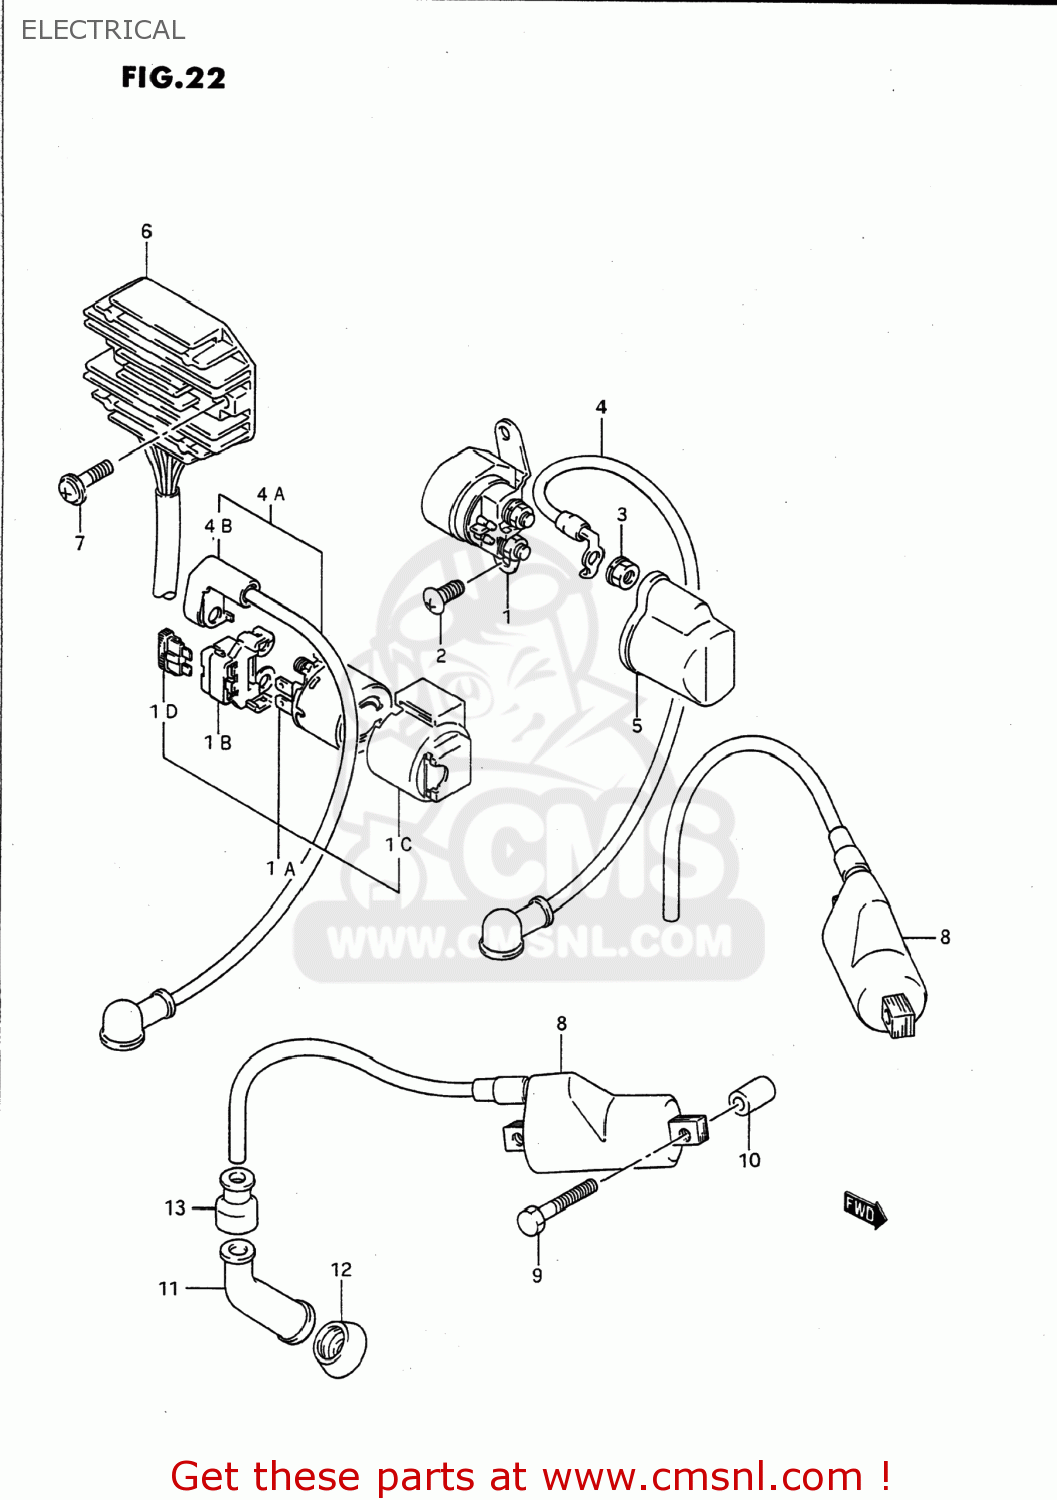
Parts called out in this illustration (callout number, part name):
1	RELAY ASSY,STARTING MOTOR
1A	RELAY ASSY,STARTING MOTOR
1B	TERMINAL,RELAY
1C	BRACKET,STARTING MOTOR RELAY
1D	FUSE(20A)
2	SCREW
3	NUT
4	WIRE,STARTER MOTOR LEAD
4A	WIRE,STARTER MOTOR LEAD
4B	CAP,STARTER RELAY TERMINAL
5	CAP,STARTER RELAY
6	RECTIFIER ASSY
7	SCREW
8	COIL ASSY,IGNITION
9	BOLT
10	SPACER(6.2X12X18)
11	CAP,SPARK PLUG
12	SEAL,SPARK PLUG CAP
13	SEAL,HIGH TENSION CORD
